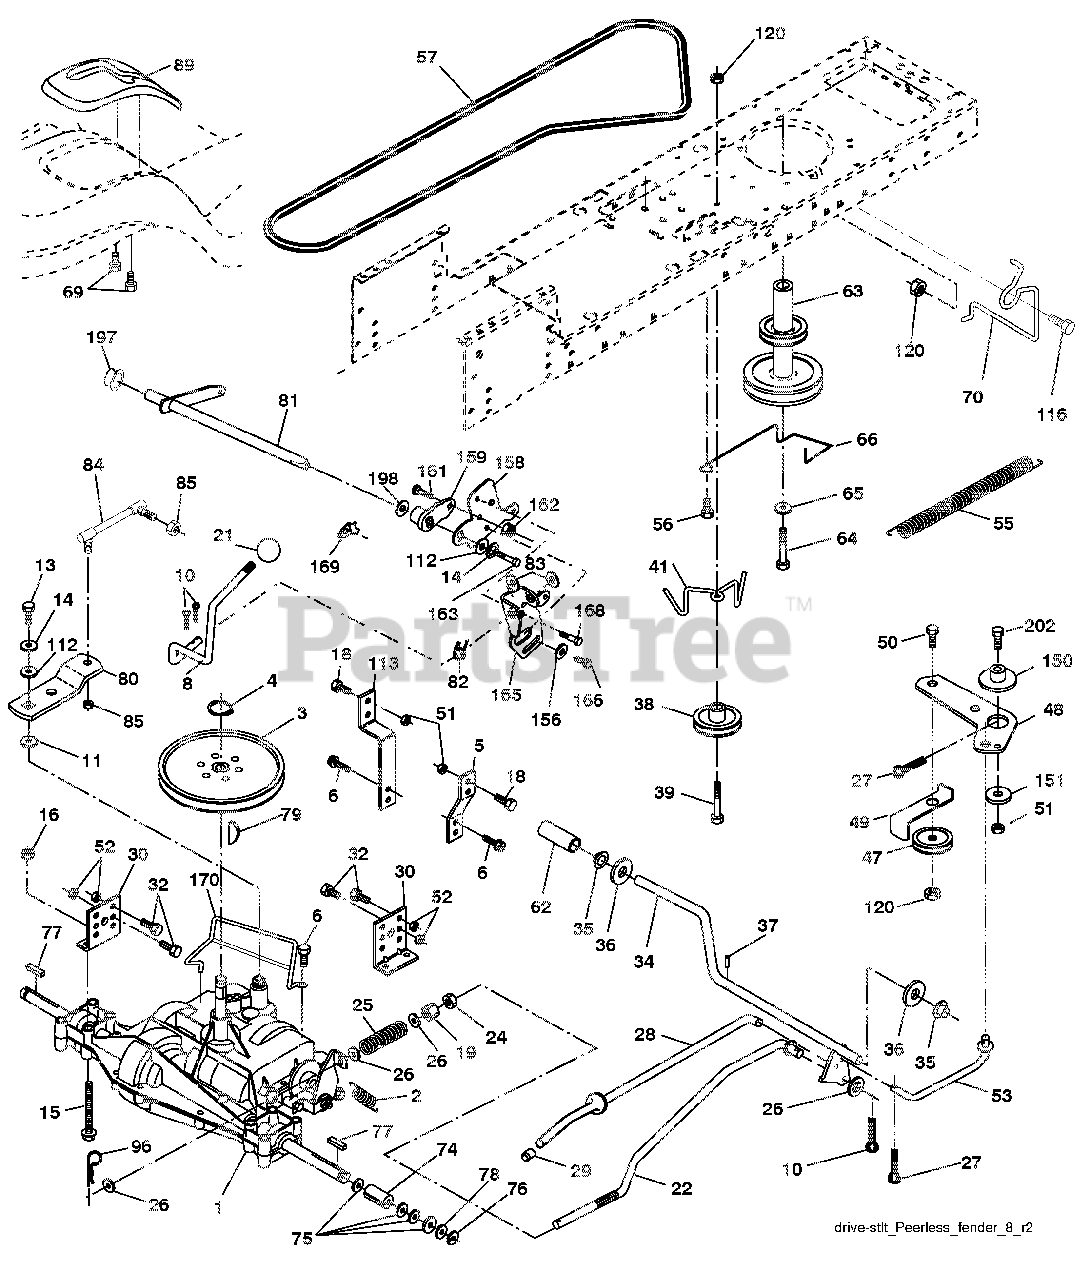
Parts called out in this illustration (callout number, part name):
1	TRANSAXLE PEERLESS 206-545C
2	Spring Return Brake T/a Zinc
3	PULLEY.TRANSAXLE.18/20"TIRES
4	Ring, Retainer
5	Strap Torque 30 Degrees
6	SCREW.5/16-18X3/4.SMGML.TAP/R
8	Rod Shift Fender Adjust Lt
10	Pin Cotter 1/8 x 1 Cad
11	WASHER.PLATE.SHF..388 SQ.HOLE
13	BOLT.1/4-28 UNF.GR8.W/PATCH
14	Washer, Lock 1/4
15	BOLT.HEX.FLGHD.5/16-18.GR.5
16	Locknut, Washer Insert 5/16-18
18	Bolt Fin Hex 3/8-16 unc x 1 Gr
19	Locknut, Washer Insert 3/8-16
22	Rod Brake Blk Zinc 26 840
24	Nut, Hex, Jam 3/8-16
25	Spring Rod Brake 2 00 Zinc
26	WASHER.13/32 X 13/16 X 16 GA.
27	PIN.COTTER.1/8 X 3/4.CAD.
28	Rod Brake Parking LT/YT
29	Cap Brake Parking
30	Bracket Mtg Transaxle
32	Bolt, Hex Head 5/16-18 x 3/4
34	Shaft Asm Pedal Foot
35	BEARING.NYLON.BLK..629 ID.
36	Washer 21/32 x 1 x 16 Ga.
37	Pin Roll 3/16 x 1"
38	Pulley Composite Flat
39	BOLT.RDHD.3/8-16UNC X2-3/4 GR5
41	Keeper Belt Flat Idler
47	Pulley Idler V Groove
48	Bellcrank Asm
49	Retainer Belt Style Spring
50	BOLT.CARR.SH.3/8-16X1-1/2.GR5
51	Nut, Hex, Crownlock 3/8-16
52	Nut, Hex, Crownlock 5/16-18
53	Link Clutch
55	SPRING.RETURN.CLUTCH.6.75
56	Screw 3/8-16 x <
57	V-Belt Ground Drive
62	COVER.PEDAL.BLK.ROUND
63	Engine Pulley
64	BOLT.HEX.7/16-20X4XGR5-1.5THR.
65	WASHER.LOCK.HVY HLCL.SPR.7/16
66	Keeper Belt Engine Foolproof
69	SCREW.HEX.WSH.HI-LO.1/4X1/2UNC
70	Guide Belt Mower Drive RH
74	SPACER.AXLE.HYDRO/PEERLES
75	WASHER.25/32 X 1 1/4 X 16 GA.
76	E-RING.#5133-75
77	KEY.SQUARE.2.0 X .1845/.1865
78	WASHER.25/32 X 1-5/8 X 16GA.
79	Key Woodruff #9 3/16 x 3/4
80	Arm Shift
81	Shaft Asm Cross Tapered Pmst/2
82	Spring Torsion T/a
83	Washer 17/32 x 3/4 x 16 Ga.
84	Link Transaxle
85	NUT.LOCK.CENTER.1/4-28 FNTHD.
89	Console Shift STLT
96	Retainer Spring
112	WASHER.9/32 X 3/4 X 10 GA.
113	Strap Torque LT
116	Bolt, Carriage 3/8-16 x 1
120	Nut, Hex, Flangelock 3/8-16
150	Spacer Retainer
151	WASHER.13/32 X 2 X 10 GA.
156	Washer Srrted 5/16ID x 1.125
158	Bracket Shift Mount
159	Hub Tapered Flange Shift Lt
161	Bolt Rdhd Sqnk 1/4-20 x 3/4
162	Nut Crownlock 1/4-20 unc
163	Bolt Hex Fin 1/4-20 unc x 1 Gr
165	Bracket Pivot Lever
166	Screw 5/16-18 x 5/8
168	Bolt Shoulder 5/16-18 x .561
169	Plate Fastening
170	Keeper Belt Transaxle Gear
197	Nyliner Snap-In
198	Washer Nyliner
202	BOLT.RDHD.3/8-16UNCX1-3/4.GR5
